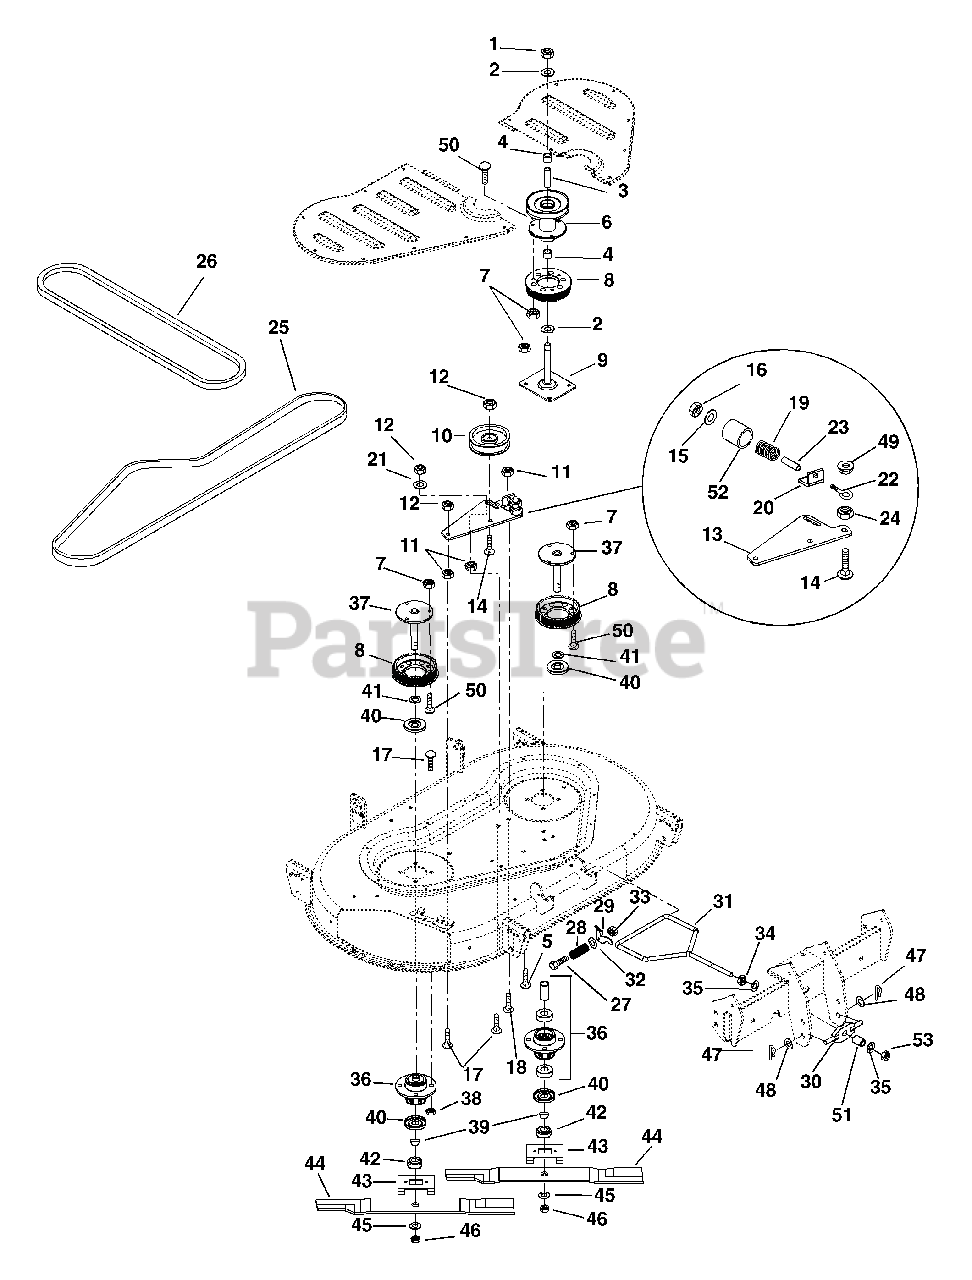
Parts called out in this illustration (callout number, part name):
1	Nut-Locking-Nylon .625-18
2	Washer-Flat-Steel .630 x 1.00 x .062
3	Spacer .64 x .88 x 4.07
4	Bearing .625 x 1.37 x .43
5	Bolt-Round Head Square Neck .31-18 x .75
6	Jackshaft
7	Nut-Locking-Center.31-18
8	Sprocket-Drive
9	Weldment-Plate Mount
10	Assembly-Idler Pulley
11	Nut-Locking-Jam-Center .38-16
12	Nut-Locking-Top-Flange .38-16
13	Arm-Idler
14	Bolt Round Head Square Neck .38-16 x 1.75 Grade 5
15	Washer-Flat-Steel .438 x 1.00 x .083
16	Nut, Locking-Center .38-16
17	Bolt-Round-Head Square Neck .38-16 x 1.25 Grade 5
18	Bolt-Round-Head Square Neck .38-16 x .75 Grade 5
19	Spring-Compression .125 x .78 x 1.25
20	Bracket-Belt Adjustment
21	Washer-Flat-Steel .438 x 1.00 x .083
22	Bolt-Eye .375-16 x 2.50
23	Spacer .39 x .50 x .86
24	Nut-Locking-Nylon .38-16
25	Belt-Cog
26	Belt-V A-RMA
27	Bolt-Hex .25-20 x 1.25 Grade 5
28	Spring-Compression .058 x .68 x .75
29	Retainer-Brace
30	Weldment-Front Mount
31	Rod Link
32	Washer-Flat-Steel .312 x .734 x .065
33	Nut-Locking-Nylon .25-20
34	Nut-Locking-Center ..50-13
35	Washer-Flat-Steel .563 x 1.38 x .109
36	Assembly-Spindle Housing
37	Weldment-Spindle Shaft
38	Nut-Locking-Top-Flange .38-16
39	Key Woodruff .188 x .625 x .31
40	Bearing-Slinger
41	Washer-Flat-Steel .755 x 1.25 x .125
42	Hub-Retainer
43	Tray-Blade
44	Blade, Mulch 22"
44	Blade-22" Low Lift-CE
45	Washer-Locking .75 x .188
46	Nut-Jam .75-10
47	Clip-Spring
48	Washer-Flat-Steel .531 x 1.06 x .095
49	Nut-Locking-Flange Grade.A .375-16
50	Bolt-Round-Head Square Neck .31-18 x 1.00 Grade 5
51	Bushing-Sleeve .50 x .74 x .53
52	Spacer .803 x 1.09 x .877
53	Nut-Locking-Nylon .50-13
